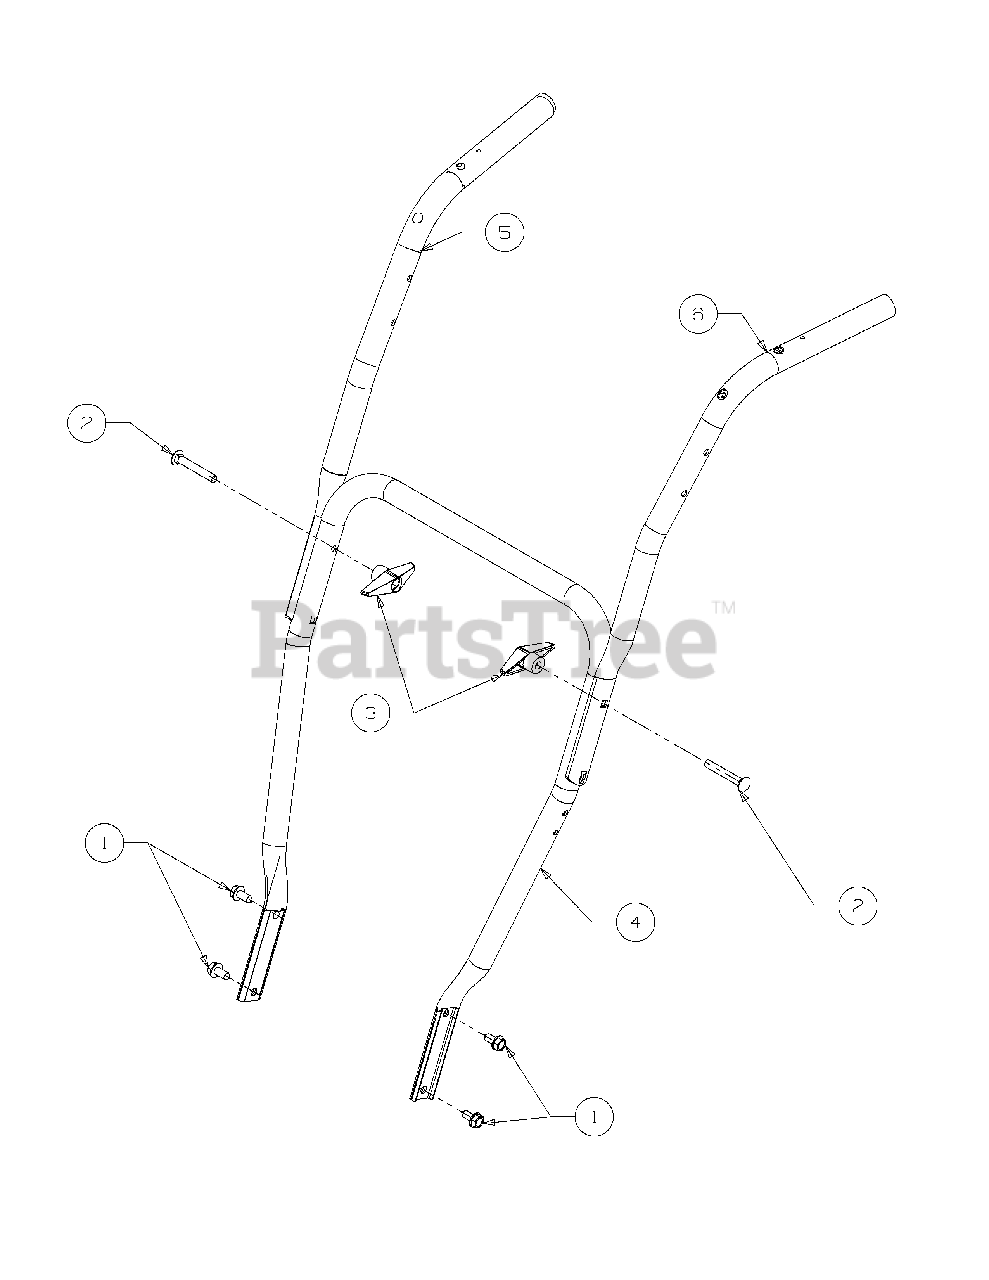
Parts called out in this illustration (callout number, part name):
1	SCREW 5/16-18 x .750
2	Bolt-Carriage 5/
3	Knob-Wing Nut
